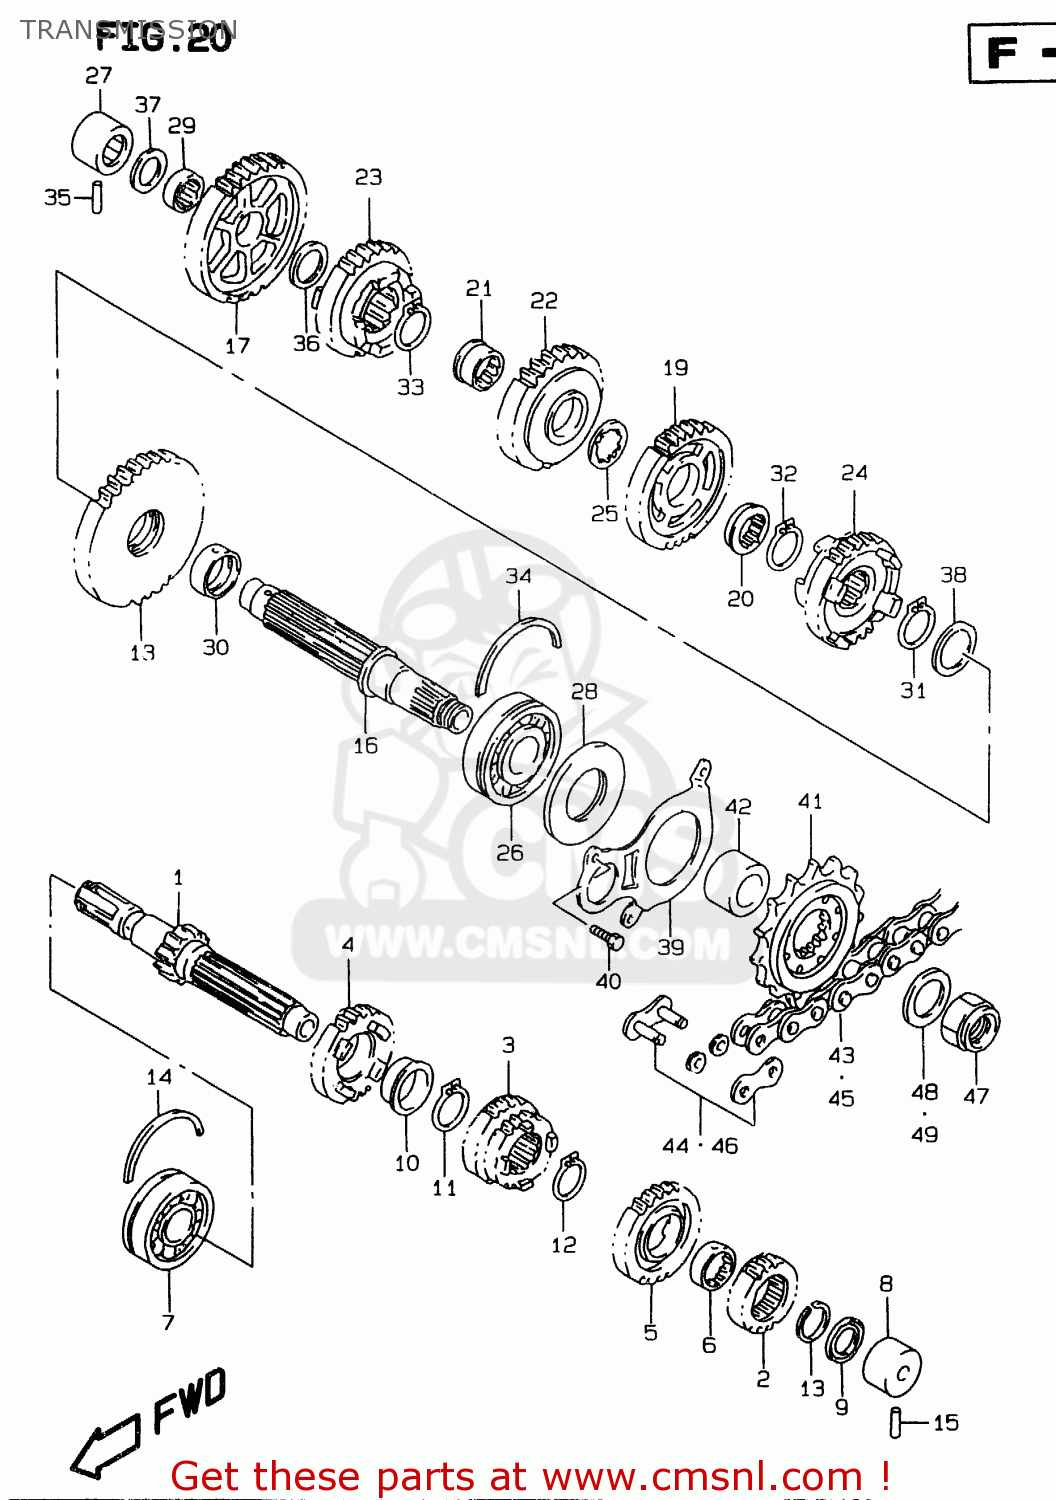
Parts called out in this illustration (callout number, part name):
1	SHAFT,COUNTER
2	GEAR,SECOND DRIVE
3	GEAR,3RD & 4TH DRIVE
4	GEAR,5TH DRIVE
5	GEAR,6TH DRIVE
6	BUSH,6TH DRIVE GEAR
7	BEARING(25X62X17)
8	BEARING
9	SEAL,OIL(20X31.2X2.7)
10	BUSH(28X32X2)
11	CIRCLIP
12	CIRCLIP
13	CIRCLIP
14	C RING
15	PIN
16	SHAFT,DRIVE
17	GEAR,1ST DRIVEN
18	GEAR,2ND DRIVEN
19	GEAR,3RD DRIVEN(NT:33)
20	BUSH
21	BUSH
22	GEAR,4TH DRIVEN(NT:30)
23	GEAR,5TH DRIVEN(NT:29)
24	GEAR,6TH DRIVEN(NT:28)
25	WASHER,LOCK
26	BEARING(28X70X18)
27	BEARING(20X34X20)
28	SEAL,OIL(34.8X70X6)
29	BUSH(22X26X9)
30	BUSH(28X32X9.5)
31	CIRCLIP
32	CIRCLIP
33	CIRCLIP
34	C RING
35	PIN
36	WASHER
37	WASHER
38	SHIM(28X38X1)
39	RETAINER,DRIVE SHAFT OIL SEAL
40	BOLT
41	SPROCKET,ENGINE(16T)
42	SPACER,ENG SPROCKET
43	CHAIN ASSEMBLY RK50MFOZ1.1
44	JOINT SET,DRIVE CHAIN
45	CHAIN ASSEMBLY RK525R0Z2.1
46	JOINT SET,DRIVE CHAIN
47	NUT
48	WASHER,THRUST
